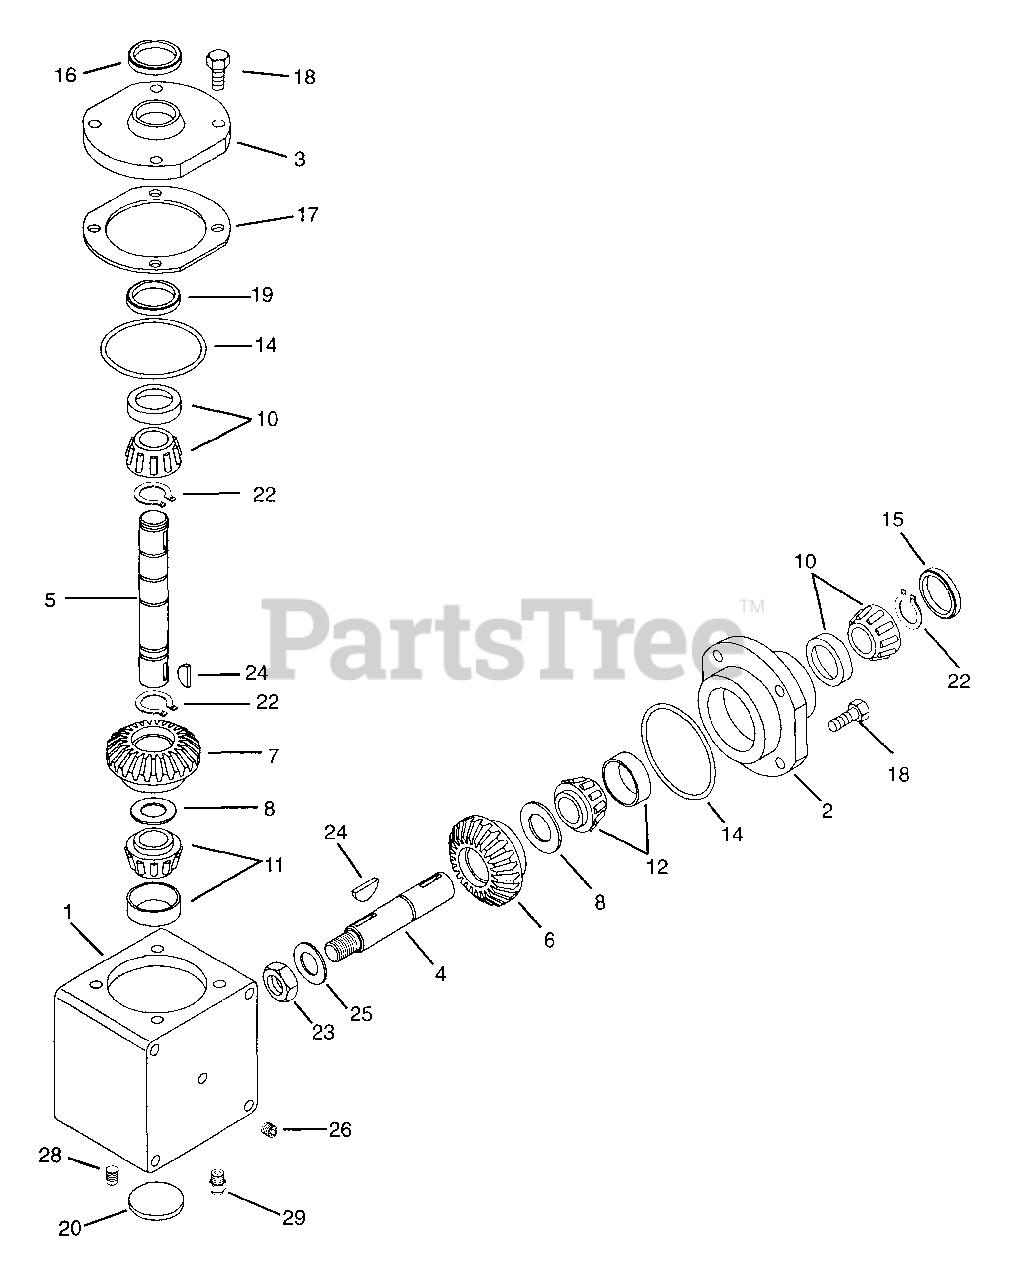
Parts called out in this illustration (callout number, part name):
1	Housing, Right Angle Drive
2	Cap, Retainer
3	Cap, Retainer
4	Shaft, Input (5.38" long)
5	Shaft, Output (7.89" long)
6	Gear, Spiral Bevel (25 teeth)
7	Gear, Spiral Bevel (26 teeth)
8	Shim (1-1/2" O.D. x 1-1/64" I.D. x .002 thick)
9	Shim (2.000" O.D. x 1.531" I.D. x .002 thick)
10	Bearing & Cup Assy.
11	Bearing & Cup Assy.
12	Bearing & Cup Assy.
14	"O" Ring
15	Seal, Oil
16	Seal, Oil
17	Shim, Cap Retainer
18	Screw, Hex, Head .31-18 x 1
19	Ring Load
22	Ring, Retaining
23	Jam Nut, 3/4-16
24	Key, Woodruff
25	Washer, Flat 1
26	Plug, Pipe, .25-18
28	Plug, Pipe, .12-27
29	Valve, Relief
